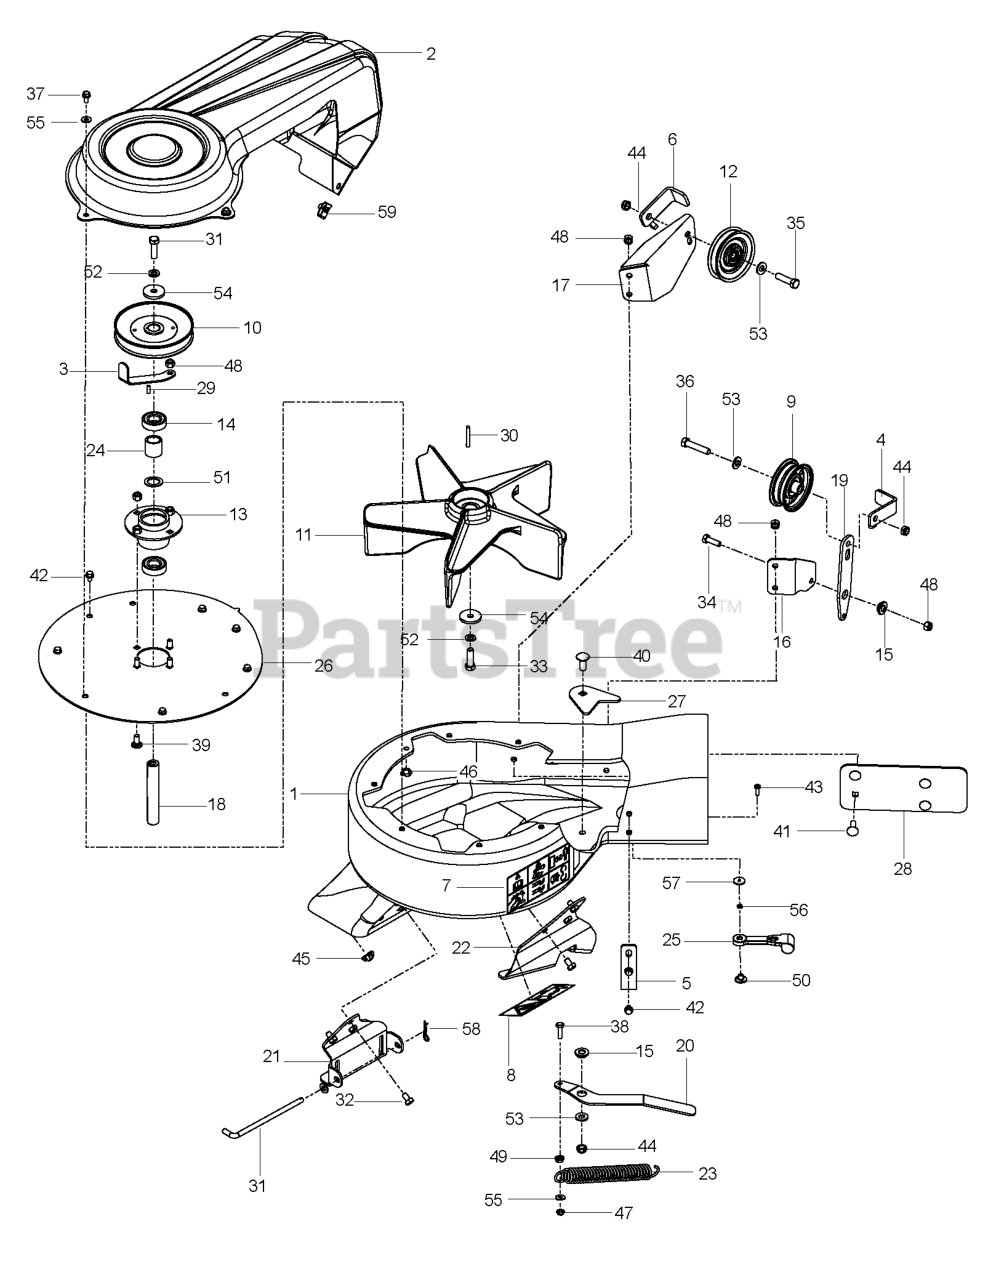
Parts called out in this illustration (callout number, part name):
1	BLOWER.HOUSING.W/DECALS.COLLEC
2	COVER, BELT
3	KEEPER, BELT, OUTER
4	KEEPER FLAT UPPER BLK
6	KEEPER FLAT LOWER BLACK
7	DECAL, EURO WARNING
8	EURO DECAL, IMPELLER
9	PULLEY, IDLER, BACKSIDE
11	IMPELLER.COLLECTION.BLOWER.BLA
13	HUB, BEARING
16	MOUNT.IDLER.UPPER
17	MOUNT IDLER LOWER
18	SHAFT, IMPELLER
20	ARM, TENSION
21	BRKT, MT, FRONT
22	BRKT, MT, REAR
25	LATCH.HOOD.
26	PLATE, OUTER
27	PLATE, BACKING
28	PLATE.BACKING.BLACK
29	KEY, 3/16 X 1/2
30	KEY-SQ. 3/16 X 1 1/2
32	HCS 5/16-18 X 1/2 GR 5 ZD
33	BLADE BOLT
34	BOLT.FIN.HEX.5/16-18UNC X 1.00
35	BOLT
36	BOLT, HCS 3/8-16X1-3/4
37	SCREW
38	BOLT
39	RP BOLT 5/16-18 X3/4 ZN/YEL GR
40	BOLT D
41	BOLT
42	HWST 1/4C X 3/8
43	SCREW
44	NUT HEX 3/8-16 NYLON, THIN
45	NUT 5/16-18 TEE
46	NUT 1/4-20 TEE
47	JAM NUT 1/4C (2 2 PW01)
48	NUT.71038.31-18.HEX.NYLOCK
49	NUT.FLANGE.1-4-20-SERR
50	NUT 10-24 WELD PLATED
51	WASHER .787 X 1.125 X .06
52	LOCKWASHER
53	WASHER
54	WASHER, HARDENED
55	WASHER
56	WASHER - 3/16 LOCK ZD
58	HAIRPIN #2
59	U-CLIP 5/16-18 NUT RETAINER
